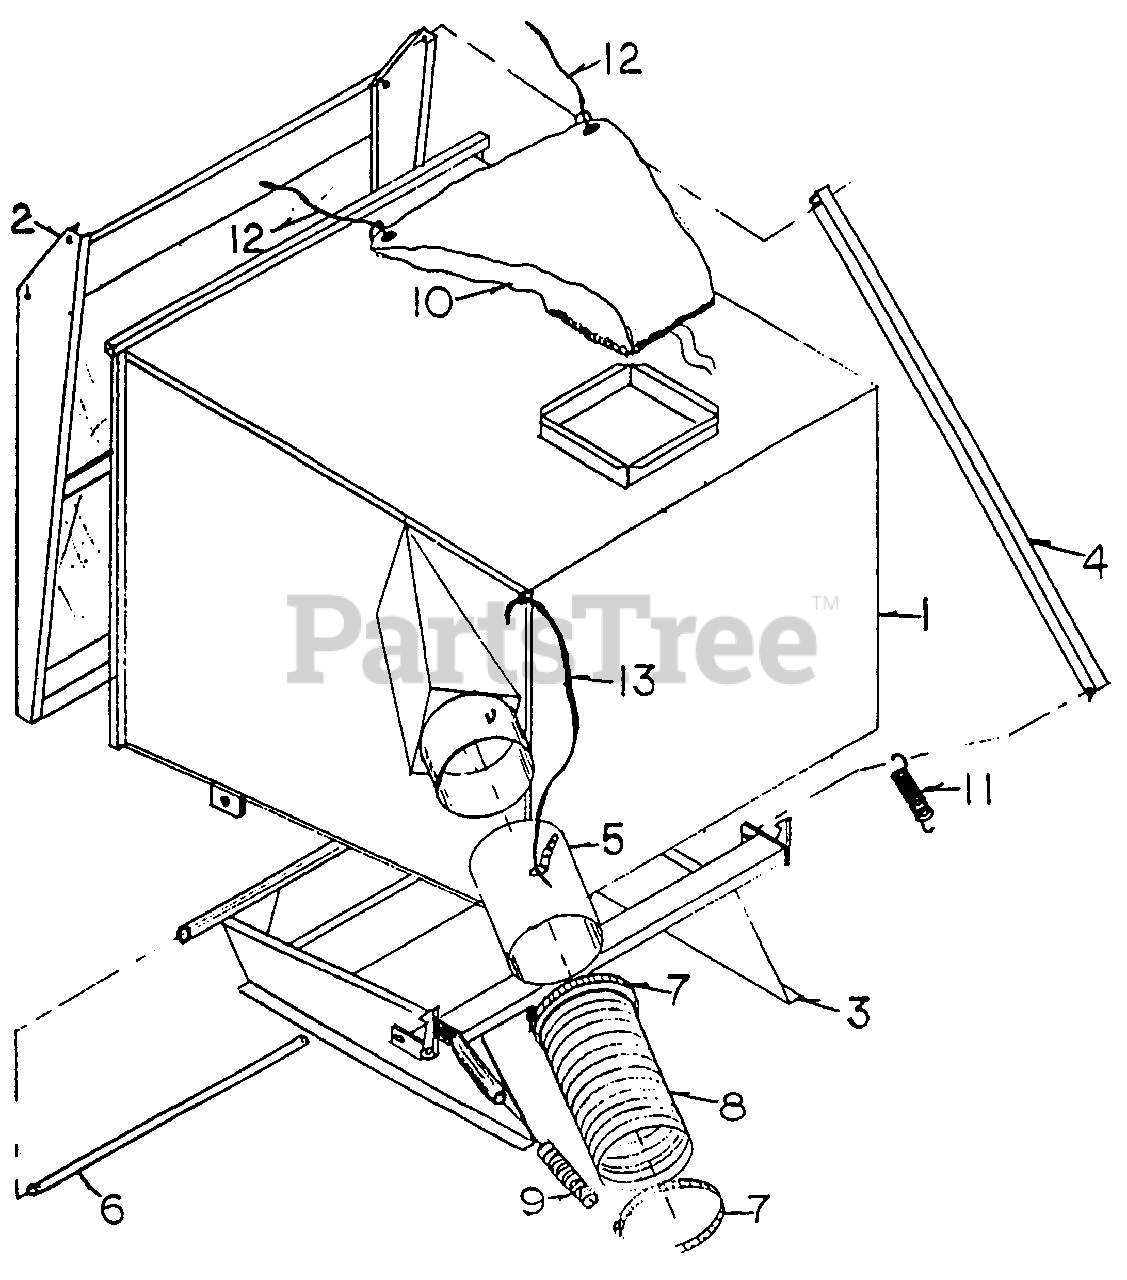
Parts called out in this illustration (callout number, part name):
1	GRASS BOX
3	BOX MOUNT
4	DOOR LINKACE
5	MALE TUBE
8	HOSE
9	HANDLE CRIP
12	BAG ROPE
13	MALE TUBE ROPE
